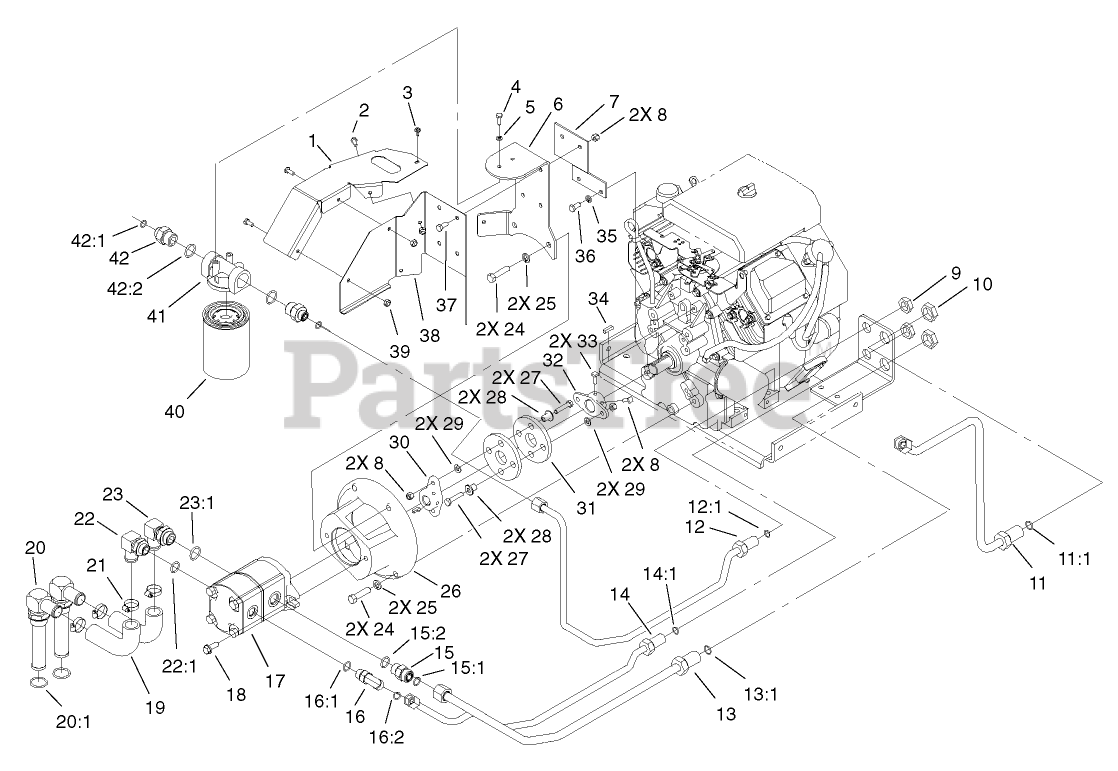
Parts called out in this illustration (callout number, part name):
1	SHIELD-HEAT
2	SCREW-HH
3	SCREW
4	SCREW-HH
5	WASHER-LOCK
6	BRACKET-SUPPORT, OIL FILTER
7	BRACKET-SUPPORT, OIL FILTER
8	NUT-LOCK, NI
9	NUT-BULKHEAD
10	NUT-LOCK, BULKHEAD
11	HYD TUBE ASM
11:1	O-RING
12	HYD TUBE ASM
12:1	O-RING
13	HYD TUBE ASM
13:1	O-RING
14	HYD TUBE ASM
14:1	O-RING
15	FITTING-STRAIGHT
15:1	O-RING
15:2	O-RING
16	FITTING-ELBOW-90 DEG
16:1	O-RING
16:2	O-RING
17	PUMP-GEAR, HYD
18	SCREW-HHF
19	HOSE-SUCTION, FORMED
20	STRAINER FITTING ASM
20:1	O-RING
21	CLAMP-HOSE
22	STEM-HOSE, 90 DEG
22:1	O-RING
23	FITTING-HYD, 90 DEG
23:1	O-RING
24	SCREW-HH
25	WASHER-LOCK
26	Mount-Pump
27	SCREW-HH
28	SPACER
29	WASHER-PLAIN
30	HUB-PUMP
31	COUPLING-RUBBER
32	HUB-ENGINE
33	SCREW-SQH
34	KEY-SQUARE
35	WASHER-LOCK
36	SCREW-HH
37	SCREW-HH
38	SHIELD-HEAT, FILTER
39	NUT-LOCK, NI
40	FILTER-OIL
41	HEAD-FILTER
42	FITTING-STR
42:1	O-RING
42:2	O-RING
